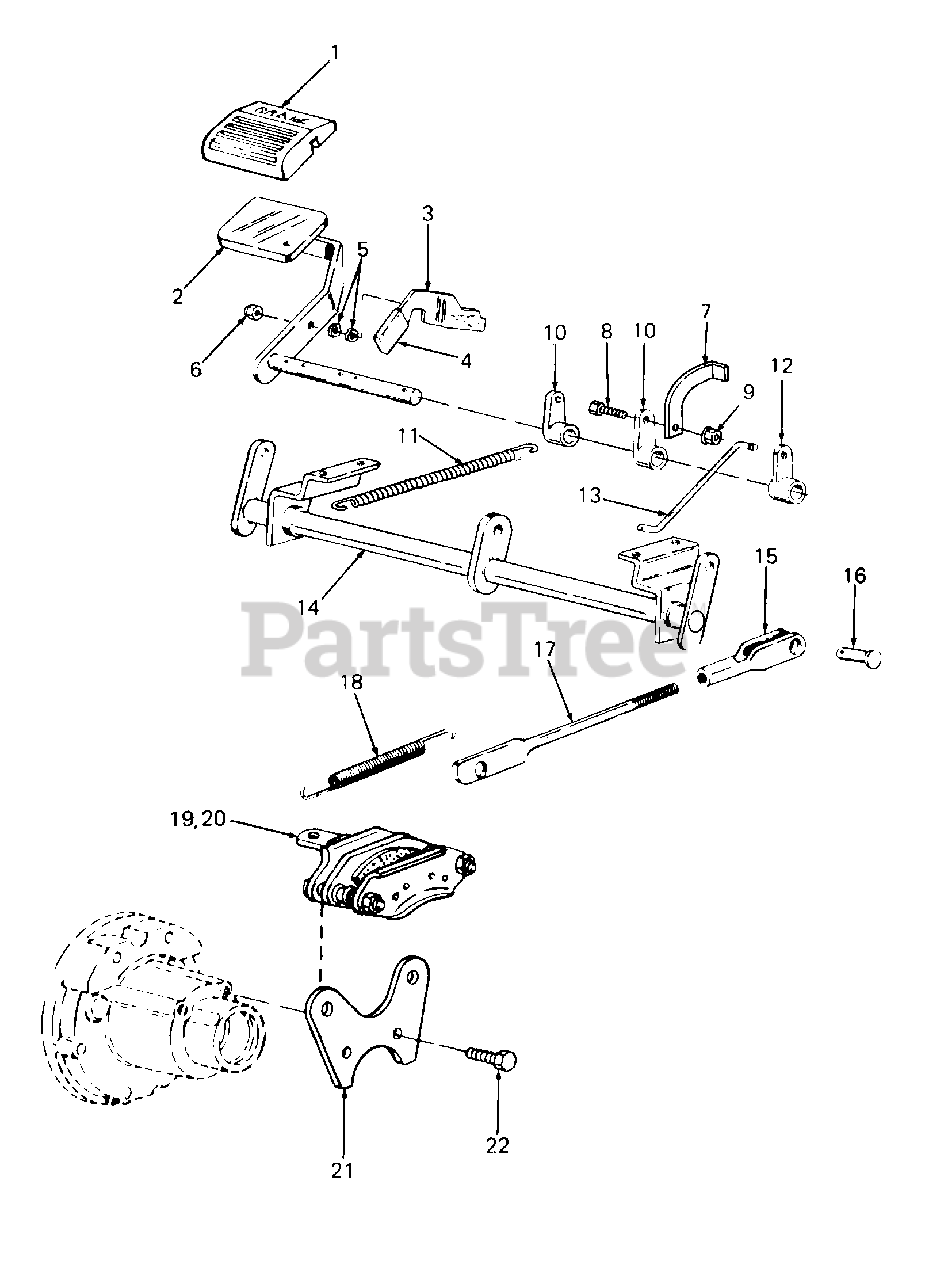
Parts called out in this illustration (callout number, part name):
1	Pad, Brake Pedal
2	Pedal Assy, Brake
5	Washer, Wave, 1/4 Dia
6	Nut, Hex Insert Lock, 1/4-20
8	Screw, Hex Cap, 3/8-16 X .75 Lg GR5
9	Nut, Hex Flanged Lock, 3/8-16 GR5
11	Spring, Return
15	Clevis, Adjustment
16	Pin, Clevis, 3/8 Dia X 1.0 Lg
17	Rod, Brake
18	Spring, Tension
19	Brake Kit, RH Caliper
21	Bracket, Brake Mounting
22	Screw, Hex Cap, 5/16-18 X 1.0 Lg GR5
